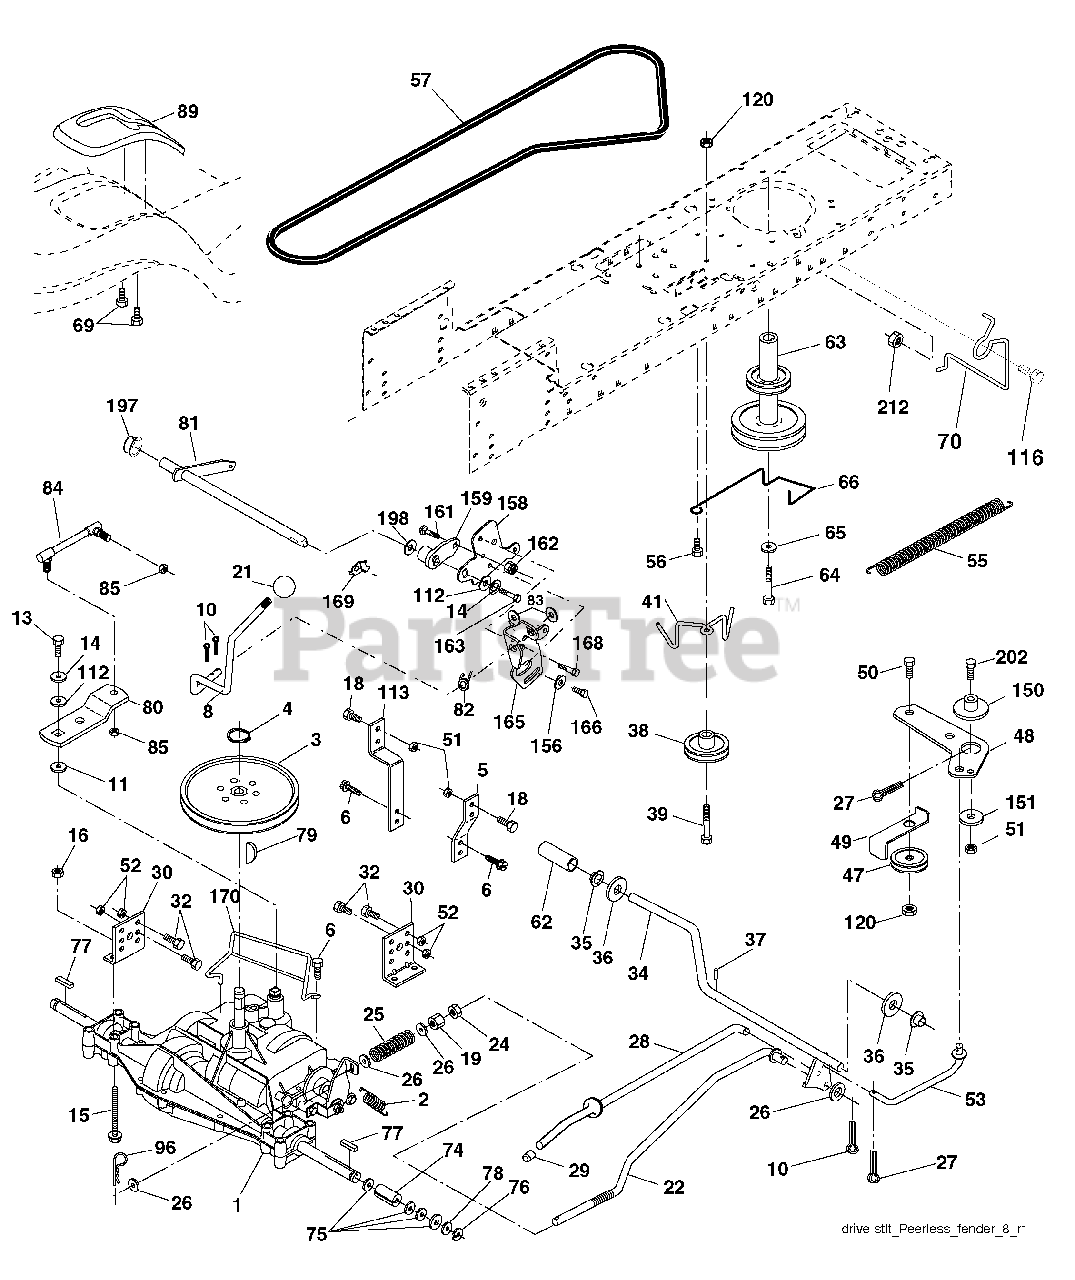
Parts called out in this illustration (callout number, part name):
2	Spring Return Brake
3	Pulley Transaxle 18"tires
4	Ring Retainer # 5100-62
5	Strap Torque 30 Degrees RH
6	Screw 5/16-18 x 3/4
8	Rod Shifter Blk
10	Pin Cotter 1/8 x 1 Cad
11	Washer Plate Shf 388 Sq Hole
13	Bolt 1/4-28 unf Gr. 8 w/Patch
14	Washer Lock Hvy Helical 1/4
15	Bolt Hex Flghd 5/16-18 Gr. 5
16	Nut 5/16-18
18	Bolt Fin Hex 3/8-16 unc x 1 Gr. 5
19	Nut lock Hex w/Ins 3/8-16 Unc
21	Knob
22	Rod Brake LT
24	Nut Hex Jam 3/8-16 unc
25	Spring Rod Brake 2 00 Zinc
26	Washer 13/32 x 13/16 x 16 Ga.
27	Pin Cotter 1/8 x 3/4 Cad
28	Rod Brake Parking LT/YT
29	Cap Brake Parking Black
30	Bracket Transmission
32	Bolt Fin Hex 5/16-18 x 3/4
34	Shaft Asm Pedal Foot Nibbed
35	Bearing Nylon Blk 629 Id
36	Washer 21/32 x 1 x 16 Ga.
37	Pin Roll 3/16 x 1"
38	Pulley Composite Flat
39	Bolt 3/8-16 x 2-3/4
41	Keeper Belt Idler
47	Pulley Idler V Groove Plastic
48	Bellcrank Clutch Grnd Drv STL
49	Retainer Belt Style Spring
50	Bolt Carr Sh 3/8-16 x 1-1/2 Gr. 5
51	Nut Crownlock 3/8-16 unc
52	Nut Crownlock 5/16-18 unc
53	Link Clutch
55	Spring Return Clutch 6 75
56	Screw 3/8-16 x 1-1/4
57	V-Belt Ground Drive
62	Cover Pedal Blk Round
63	Engine Pulley LT/YT
64	Bolt Hex 7/16-20 x 4 Gr. 5
65	Washer Lock Hvy Hlcl Spr 7/16
66	Keeper Belt Engine
69	Screw 1/4 x 1/2 unc
70	Guide Belt Mower Drive RH
74	Spacer Axle
75	Washer 25/32 x 1 1/4 x 16 Ga.
76	E-ring #5133-75
77	Key Square 2 0 x 1845/ 1865
78	Washer 25/32 x 1-5/8 x 16 Ga.
79	Key Woodruff
80	Arm Shift Transaxle
81	Shaft Asm Cross Taper
82	Spring Torsion Shift
83	Washer 17/32 x 3/4 x 16 Ga.
84	Link Transaxle
85	Nut Lock Center 1/4-28
89	Console Shift
96	Retainer Spring 1"
112	Washer 9/32 x 3/4 x 10 Ga.
113	Strap Torque 90 Degrees LH
116	Bolt Rdhd Sq Neck 3/8-16 x 1
120	Nut Lock Flg 3/8-16
150	Spacer Retainer Lt
151	Washer 13/32 x 2 x 10 Ga.
156	Washer Srrrtd 5/16 ID x 1.0 x .125
158	Bracket Shift Mount
159	Hub Shift
161	Bolt 1/4-20 x 3/4 Gr. 5
162	Nut Crownlock 1/4-20 unc
163	Bolt Hex Fin 1/4-20 unc x 1 Gr. 5
165	Bracket Pivot Lever
166	Screw 5/16-18 x 5/8
168	Bolt Shoulder 5/16-18 x .561
169	Plate Fastening
170	Keeper, Belt Transaxle
197	Nyliner Snap-In 5/8
198	Washer Nylon
202	Bolt Carr Sh 3/8-16 x 1-3/4 Gr. 5
212	Nut Hex Flg Lock
